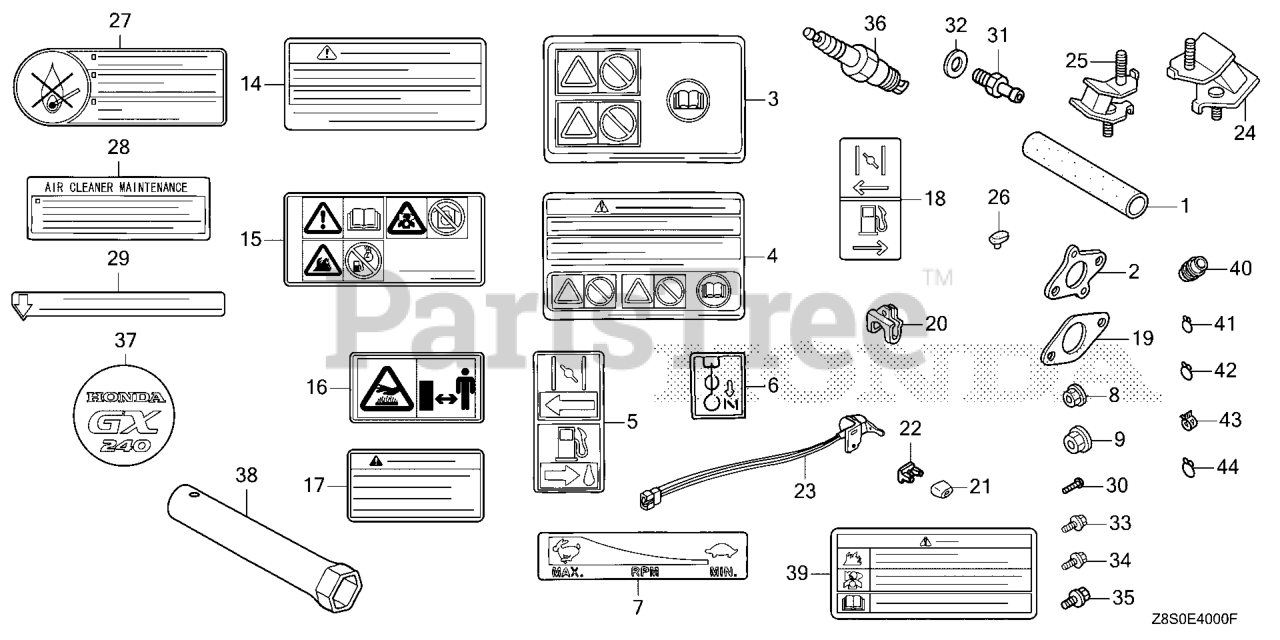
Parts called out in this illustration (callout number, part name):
14	MARK, OPERATOR CAUTION (FRENCH)(MADE IN THAI)
15	MARK, OPERATOR CAUTION (PICTOGRAPH)
16	MARK, EX. CAUTION (PICTOGRAPH)
17	MARK, EX. CAUTION (FRENCH)
39	MARK, OPERATOR CAUTION (CHINESE)
